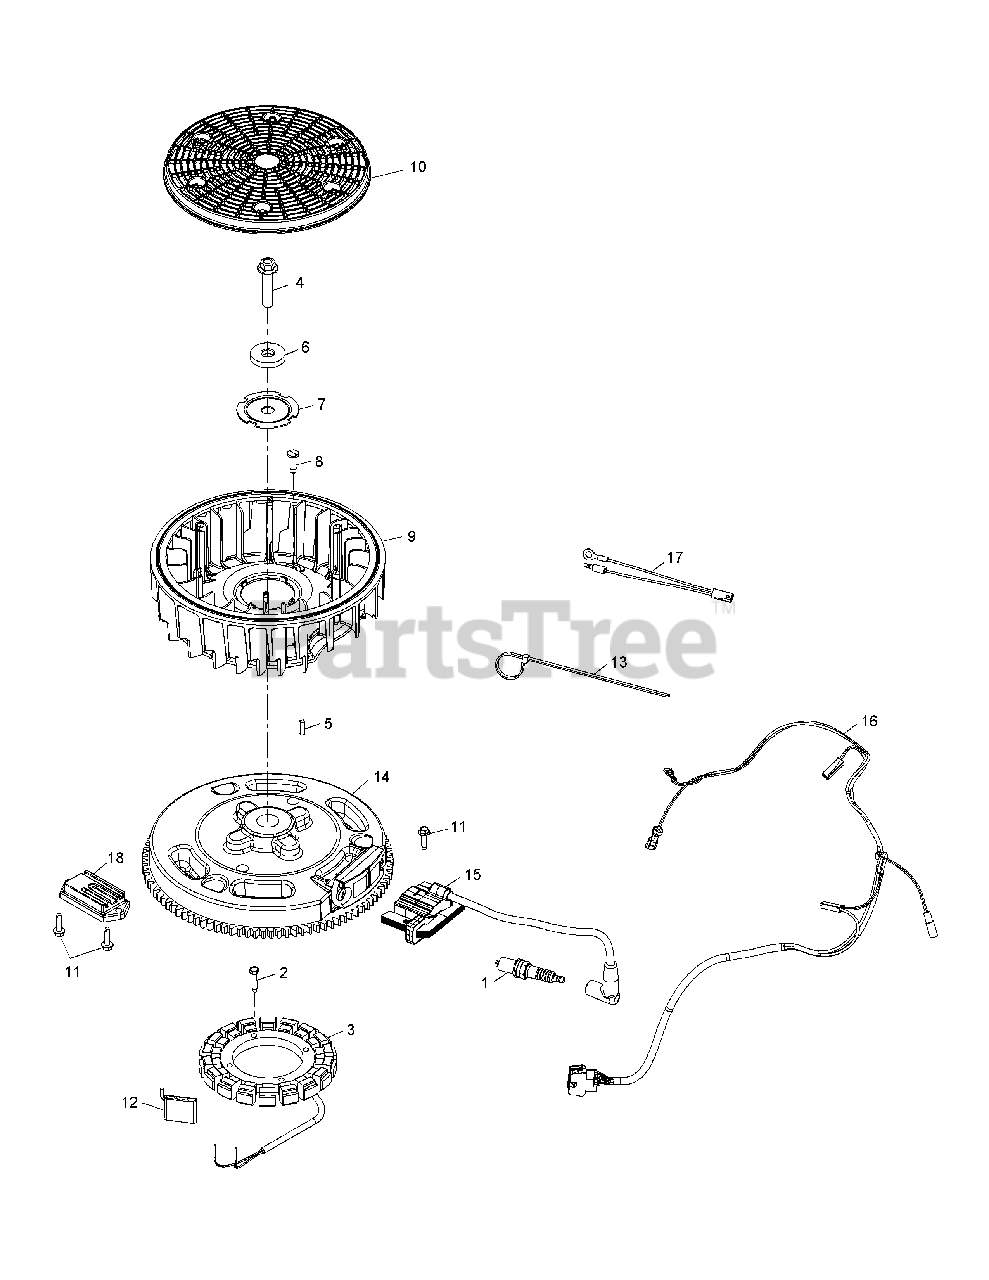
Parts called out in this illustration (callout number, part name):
2	Thread Forming Screw
3	15 Amp Stator Kit
4	Hex Flange Screw
7	Fan Mounting Plate
8	Flywheel Fan Retainer
11	Thread Forming Screw
14	Flywheel Assembly
15	Ignition Module
16	Wiring Harness
18	Rectifier Regulator
